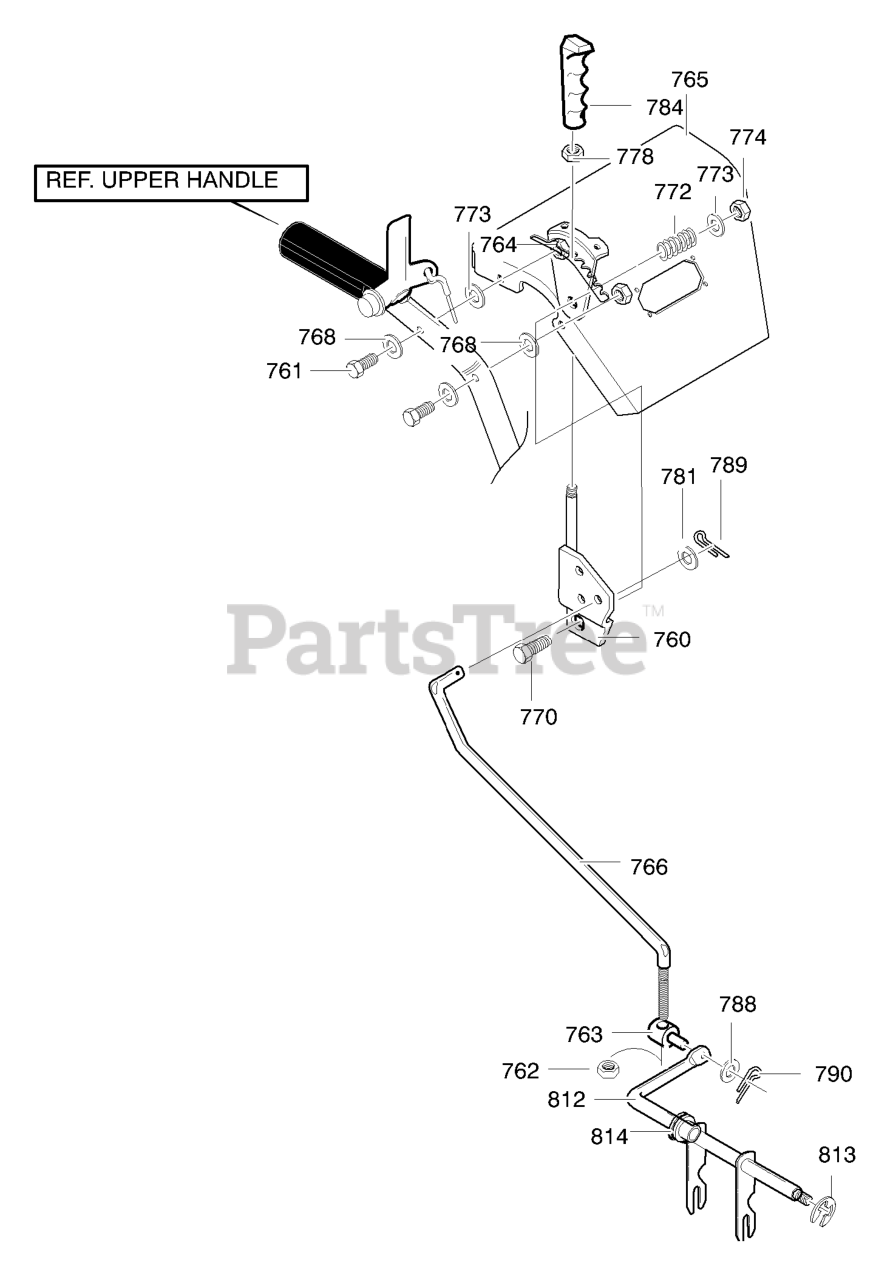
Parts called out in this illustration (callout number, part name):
760	HANDLE ASSY SPD CTRL
761	NUT, 5/16-24
762	SCREW, 5/16-18 x 1.75
763	NUT, TRUNNION
764	NUT, 5/16-18 HEXWDFLLK
765	ASSY. BAY LT
766	ROD, SPEED CONTROL
770	SCREW 3/8-16X2.00
773	FLATWASHER
774	NUT, 3/8-16 HEXNYL
778	NUT, 3/8-16 REGHEX
781	FLATWASHER
784	HANDLE 3/8-16
788	FLATWASHER
789	PIN, COTTER
790	COTTER PIN
812	ROD, ASSY YOKE
813	RING, RETAINER
814	BEARING, FLANGE
